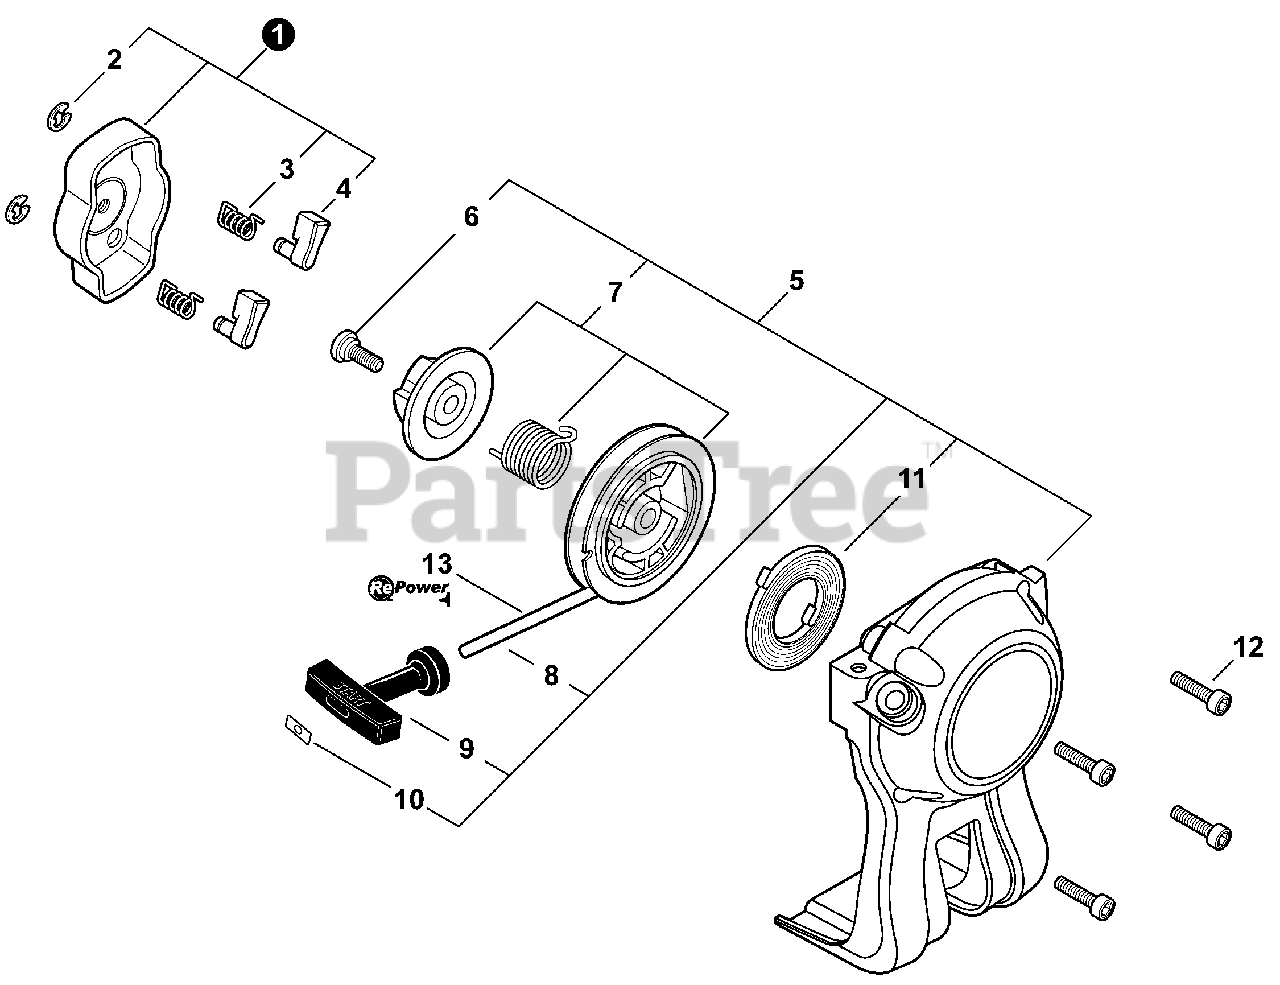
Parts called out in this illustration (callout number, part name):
1	PAWL ASSY, STARTER
2	E-RING 4
3	SPRING, RETURN
4	PAWL, STARTER
5	STARTER ASSY, RECOIL
6	SCREW
7	REEL/CAM PLATE SET
8	ROPE, STARTER
9	GRIP, STARTER
10	RETAINER, ROPE
11	SPRING, RECOIL
12	BOLT, TORX 4×16
13	BULK STARTER ROPE - Ø 3.0 MM×61 M
